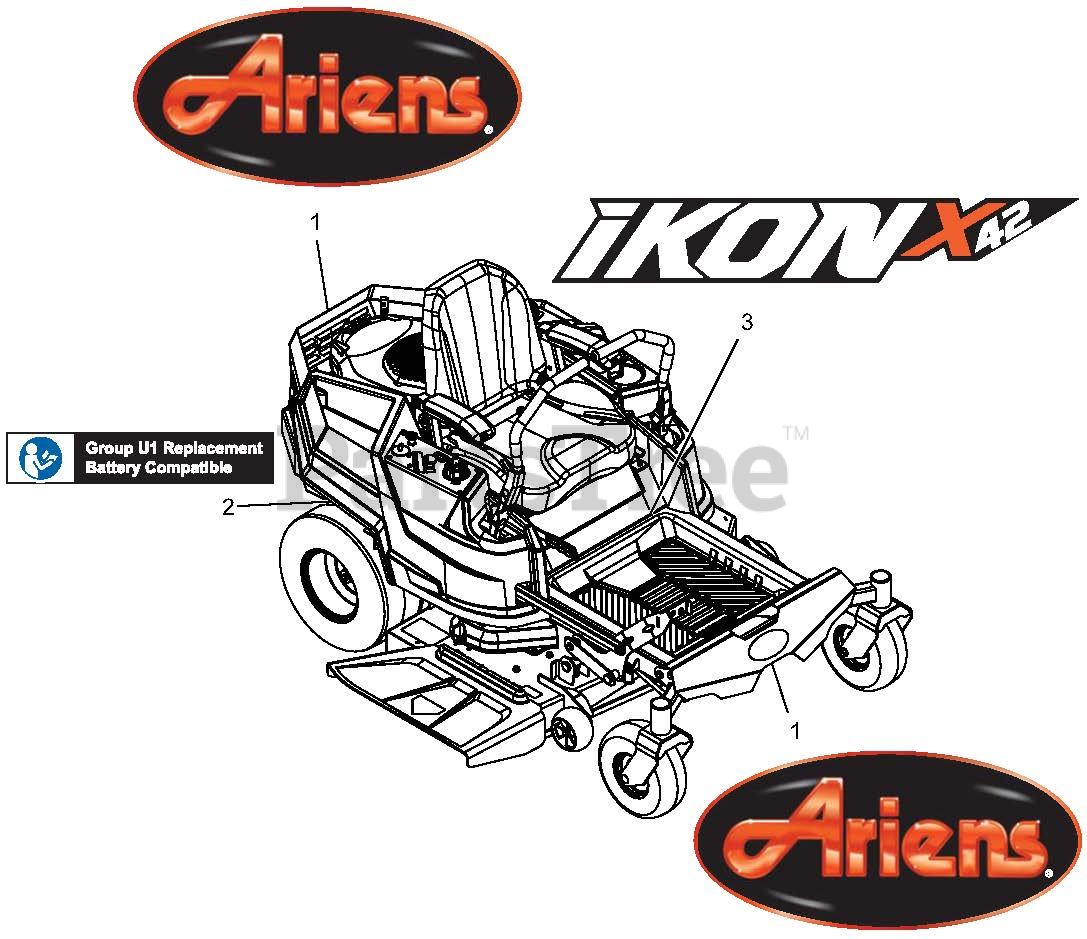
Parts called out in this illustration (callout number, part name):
1	DECAL, ARIENS JEWEL
2	DECAL, U1 BATTERY REPLACEMENT
3	DECAL, ARIENS IKON 42
